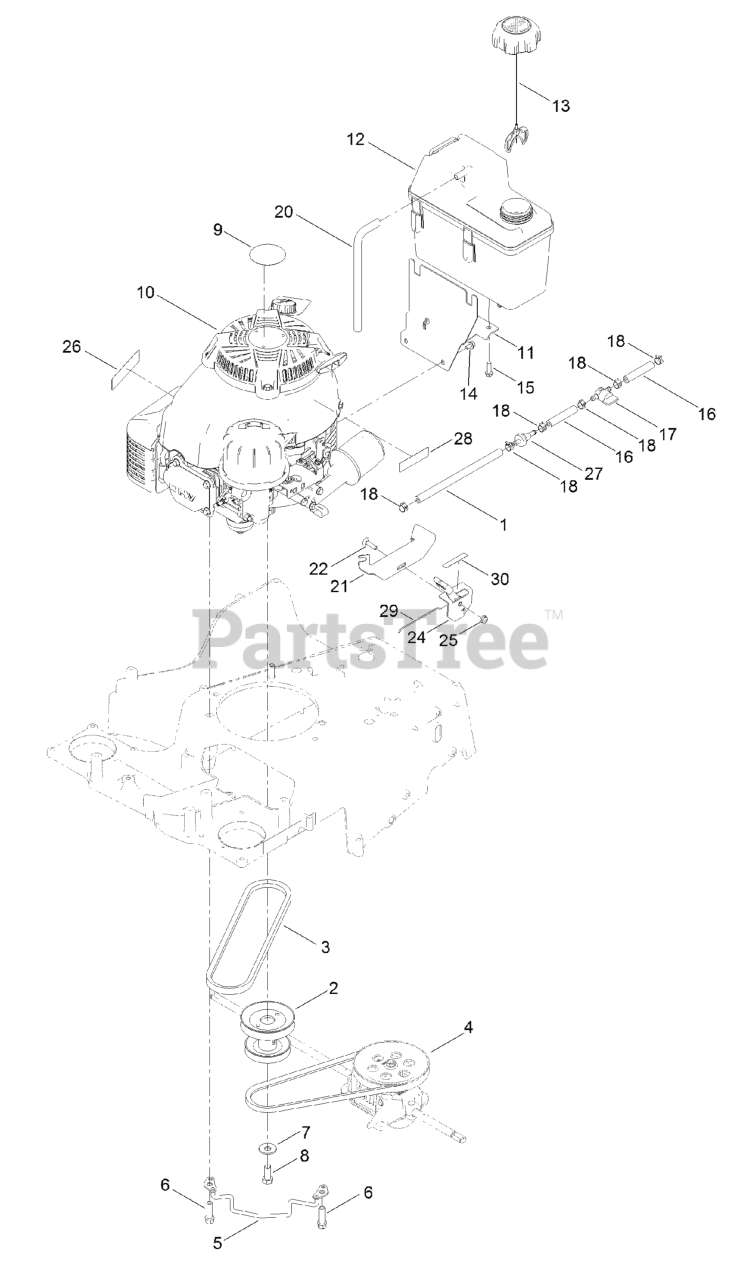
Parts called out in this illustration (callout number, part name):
1	HOSE-FUEL
2	PULLEY-ENGINE
4	BELT
6	SCREW-TAPTITE
7	WASHER-BELLEVILLE
8	SCREW-HH
11	MOUNT-TANK
12	TANK-FUEL
14	SCREW-HWH
15	SCREW-HWH
16	HOSE-FUEL
17	VALVE-FUEL
18	CLAMP-HOSE
20	HOSE-VENT, CANISTER
21	BRACKET-MOUNT, THROTTLE
22	SCREW-CARR
24	CONTROL-THROTTLE
26	DECAL-ARRESTER, SPARK
27	FILTER-FUEL
28	DECAL-WARNING, ENGINE
29	WIRE-CONTROL
30	DECAL-THROTTLE, CHOKE
